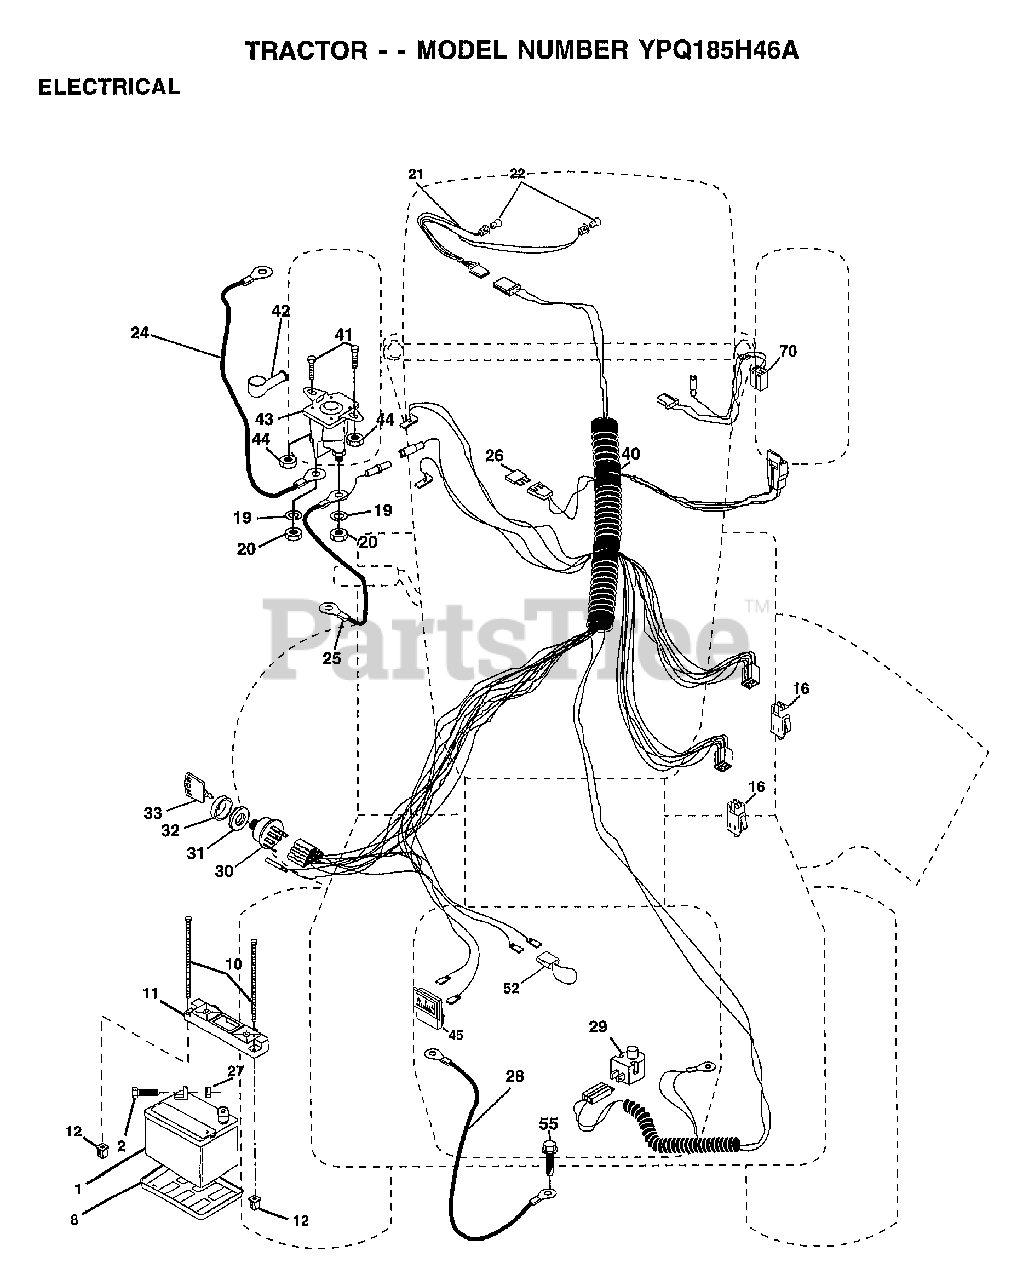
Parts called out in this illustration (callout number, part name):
2	BOLT LT
8	"TRAY T, BATTERY"
11	HOLDDOWN BATTERY
16	SWITCH INTERLOCK
20	NUT
21	HARNESS.ASM.LIGHT W/4152J
22	HEADLAMP BULB
24	"CABLE T, BATTERY"
25	CABLE.6GA.22W/16W
26	FUSE.15 AMP
27	NUT
28	CABLE.GRND.6GA.21
29	SWITCH SEAT
30	SWITCH IGN 4POS
31	NUT IGNITION
32	COVER KEY SWITCH
33	KEY
40	HARNESS.IGNITION
41	BOLT HXHD FIN
44	NUT HXKEP 1/4X20
52	PROTECTION LOOP
55	SCREW LT
70	HARNESS.ENGINE
